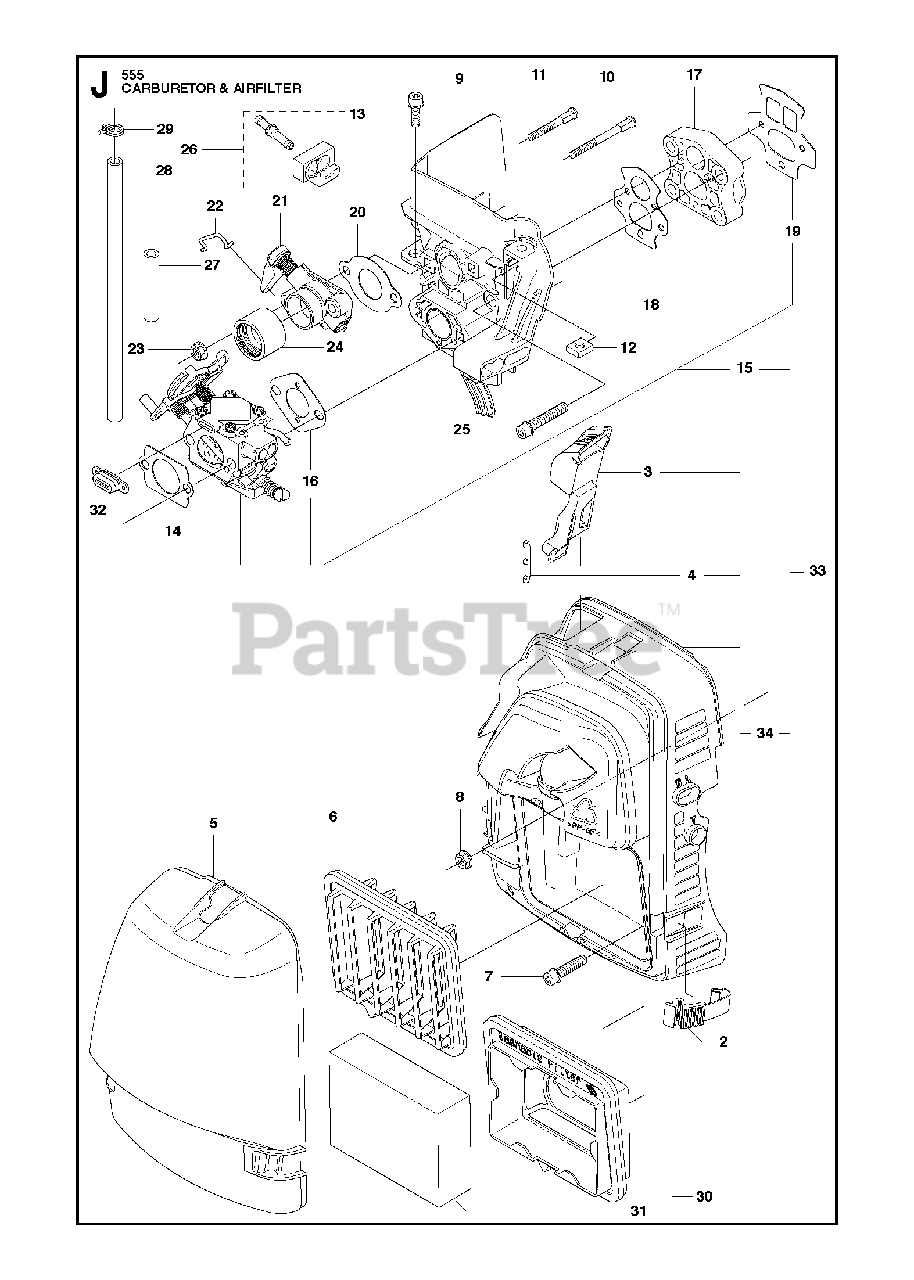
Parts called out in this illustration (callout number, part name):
2	HOLDER
3	CHOKE CONTROL
4	GROMMET
5	FILTER COVER
6	FILTER
9	INSULATION WALL
14	GASKET
15	CARBURETOR
16	GASKET
18	GASKET
19	GASKET
21	VALVE HOUSING
24	INLET PIPE
25	SCREW IHSCFM
26	GROMMET
27	FUEL HOSE STRAIGHT 35
28	RP FUEL HOSE
29	HOSE CLAMP
30	FILTER
31	FILTER
32	SEALING PLUG
33	CARBURETOR KIT
34	FILTER HOLDER KIT
